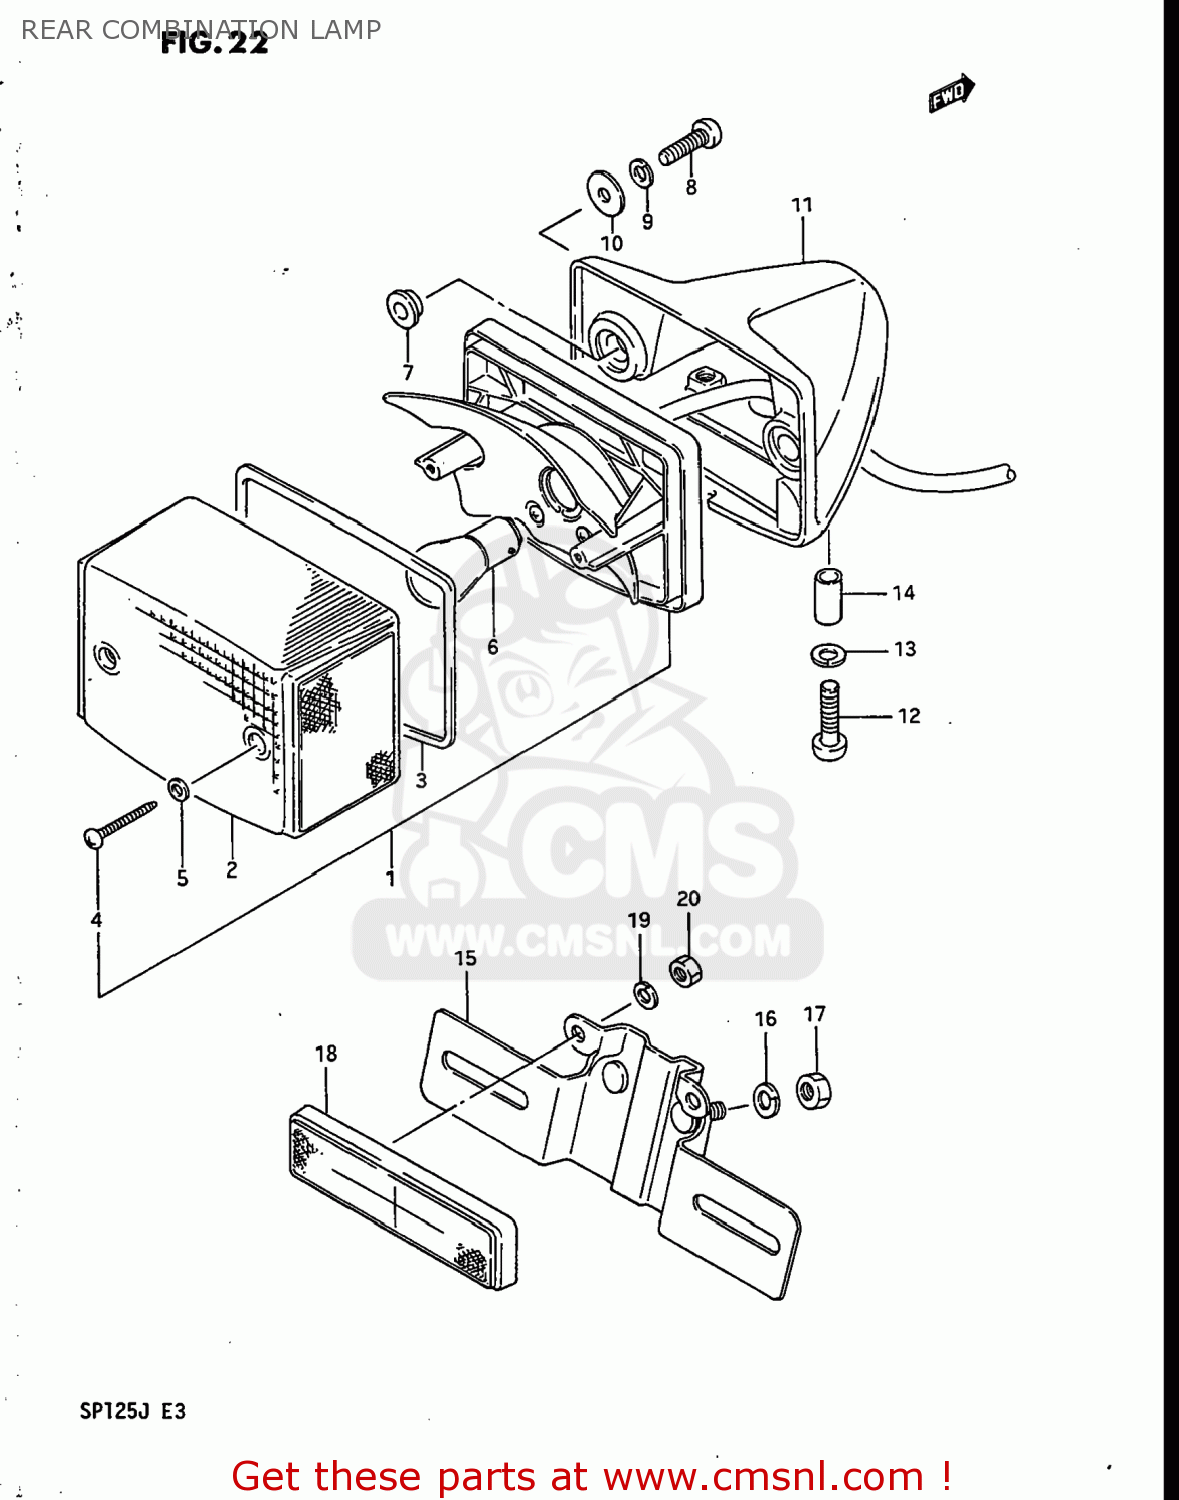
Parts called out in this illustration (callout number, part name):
1	LAMP UNIT,REAR COMBINATION
2	LENS
3	GASKET (NAS)
4	SCREW
5	GASKET (NAS)
6	BULB
7	SPACER,RR COMBI
8	SCREW 5X20
9	WASHER,LOCK
10	WASHER
11	BRACKET UNIT,TAIL LAMP
12	SCREW
13	WASHER,LOCK
14	SPACER(6.4X9.2X12)
15	BRACKET,LICENSE PLATE
16	WASHER,LOCK
17	NUT
18	REFLEX REFLECTOR,RR
19	WASHER,LOCK
20	NUT
